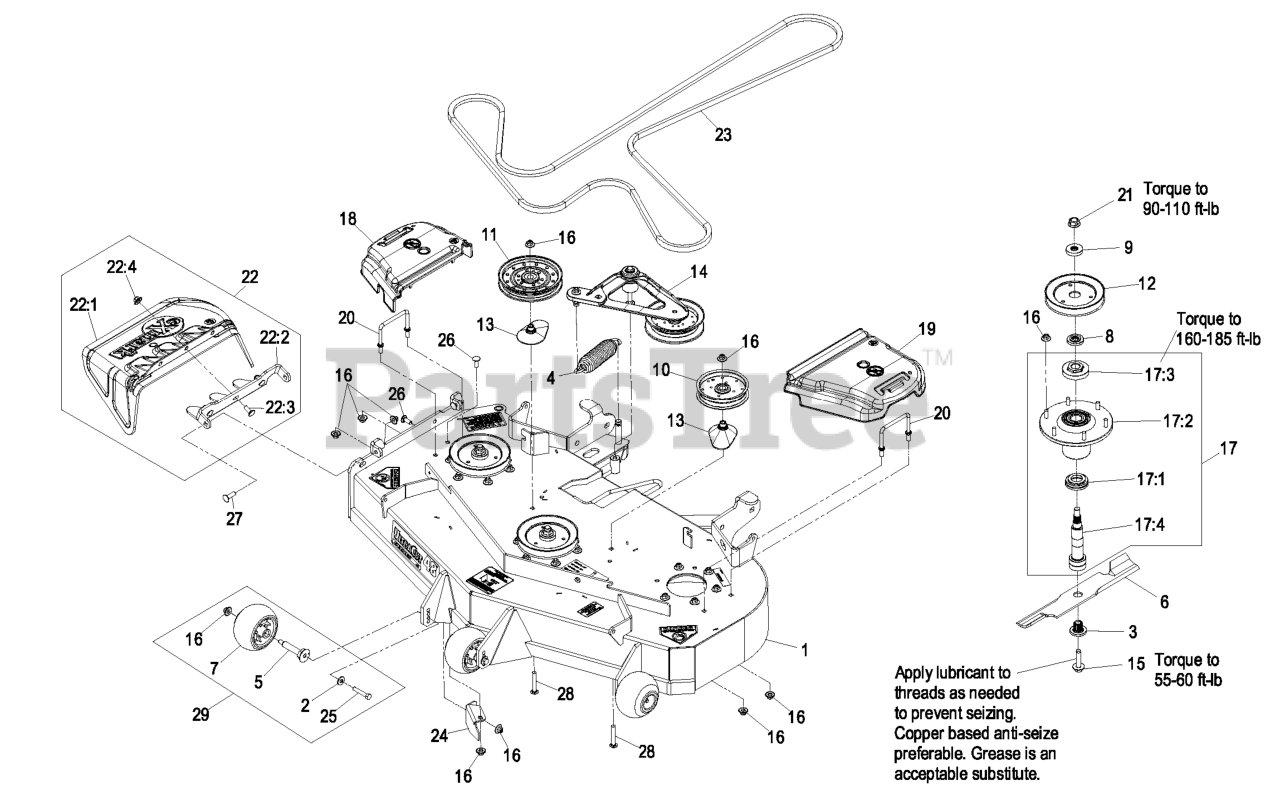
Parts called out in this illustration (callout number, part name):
1	ASM,DECK W/DECALS 48
2	WASHER-BELLEVILLE
3	BUSHING,SPLINED
7	ROLLER-SCALP, ANTI
8	SPACER,SPLINED STEPPED
9	SPACER,SPLINED
10	PULLEY-IDLER
12	SHEAVE,BLADE DRIVE 5.90
13	SPACER-PULLEY
15	SCREW,SEMS 1/2-20 X 2.19
16	Nut-Nyloc 3/8-16 Flg
17	ASM,SPINDLE HOUSING
17:1	GUARD,BOTTOM
17:2	ASM,CUTTER HOUSING
17:3	NUT, SPINDLE 7/8-14
17:4	SPINDLE,DOUBLE SPLINE
18	COVER-BELT, RH
19	COVER-BELT, LH
20	WIREFORM-COVER
21	NUT-FLANGE, CENTERLOCK
22	ASM,DISCHARGE CHUTE
22:1	CHUTE,DISCHARGE
22:2	BRACKET,DISCHARGE CHUTE
22:3	SCREW-CARR
22:4	Nut-Nyloc 3/8-16 Flg
23	BELT
24	BAFFLE,DISCHARGE
25	SCREW-HH
26	SCREW-CARR
27	Bolt-Carriage 3/8-16 X 1 1/4
28	SCREW-CARR
30	Asm, Deck Complete
